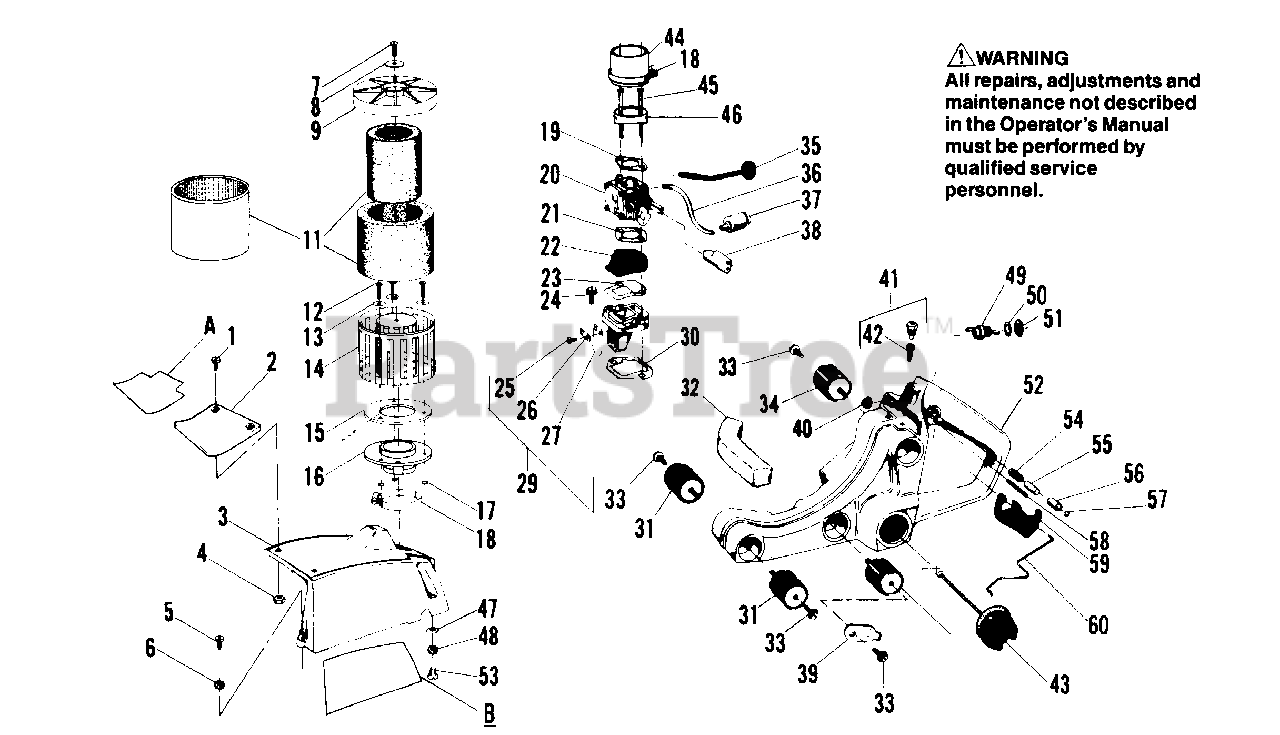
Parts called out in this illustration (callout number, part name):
1	Screw - 10 - 24 x 1/2 - Heat Shield
2	Shield - Heat
3	Cover - Cylinder
4	Nut - 10 - 24 - Heat Shield
5	Screw - Cylinder Cover - 10 x 24
6	Washer -#10 Heavy Lock - Cylinder Cover
7	Screw - 1/4 - 20 x 3/4 - Fill. Hd. - Air Filter Cover
8	Washer - Air Filter Cap
9	Cap - Air Filter
11	Air Filter Assembly
12	Screw -#10 - 24 x 3/4 - Air Filter Case
13	Washer - Air Filter Case
14	Air Filter Case (Incl. #9 & 11)
15	Gasket - Air Filter Case/Adaptor
16	Adaptor - Air Filter Case
17	Locknut - Adaptor
18	Hose Clamp
19	Gasket - Carb./Air Filter Adaptor
20	Carburetor Ass'y.
21	Gasket - Carburetor
22	Adaptor - Carb. Reed Block
23	Gasket - Carb. Adaptor/Reed Block
24	Screw - 10 - 24 x 3/4
25	Screw - 4 - 40 x 1/8 Pan Hd.
26	Stop - Reed
29	Reed Valve Ass'y. (Incl. #25, 26, 27 & 28)
30	Gasket - Reed Valve
31	Vibration Isolator - Front (Hour Glass Shape)
32	Seal - Saw Dust
33	Screw - 10 - 24 x 1/2
34	Vibration Isolator - Middle & Rear (Cylinder Shape)
35	Choke - Rod
36	Line - Fuel Pick-up
37	Fuel Pick-up Ass'y.
38	Grommet - Carb. Screws
39	Bumper - Center Isolator Mount
40	Grommet - Choke Rod
41	Vent Ass'y. - Fuel Tank (Incl. #42)
42	Check Valve - Fuel Tank Vent
43	Fuel Cap Ass'y.
44	Hose - Rubber
45	Screw - Carburetor
46	Adaptor- Carb./Air Filter
47	Washer - Cylinder Cover
48	Lockwasher - 1/4 Cylinder Cover
49	Switch - Ignition
50	Lockwasher - Switch
51	Nut - Switch Mounting
52	Fuel Tank & Handle Ass'y. (Inc. 55-58)
53	Screw-Cylinder Cover/Adaptor
54	Spring - Throttle Lock Button
55	Pin - Throttle Lock
56	Sleeve - Throttle Lock
57	E-Ring Throttle Lock
58	Pin - Trigger Shaft
59	Trigger Throttle
60	Rod - Throttle
A	Decal - Instructions
B	Decal - Warning
